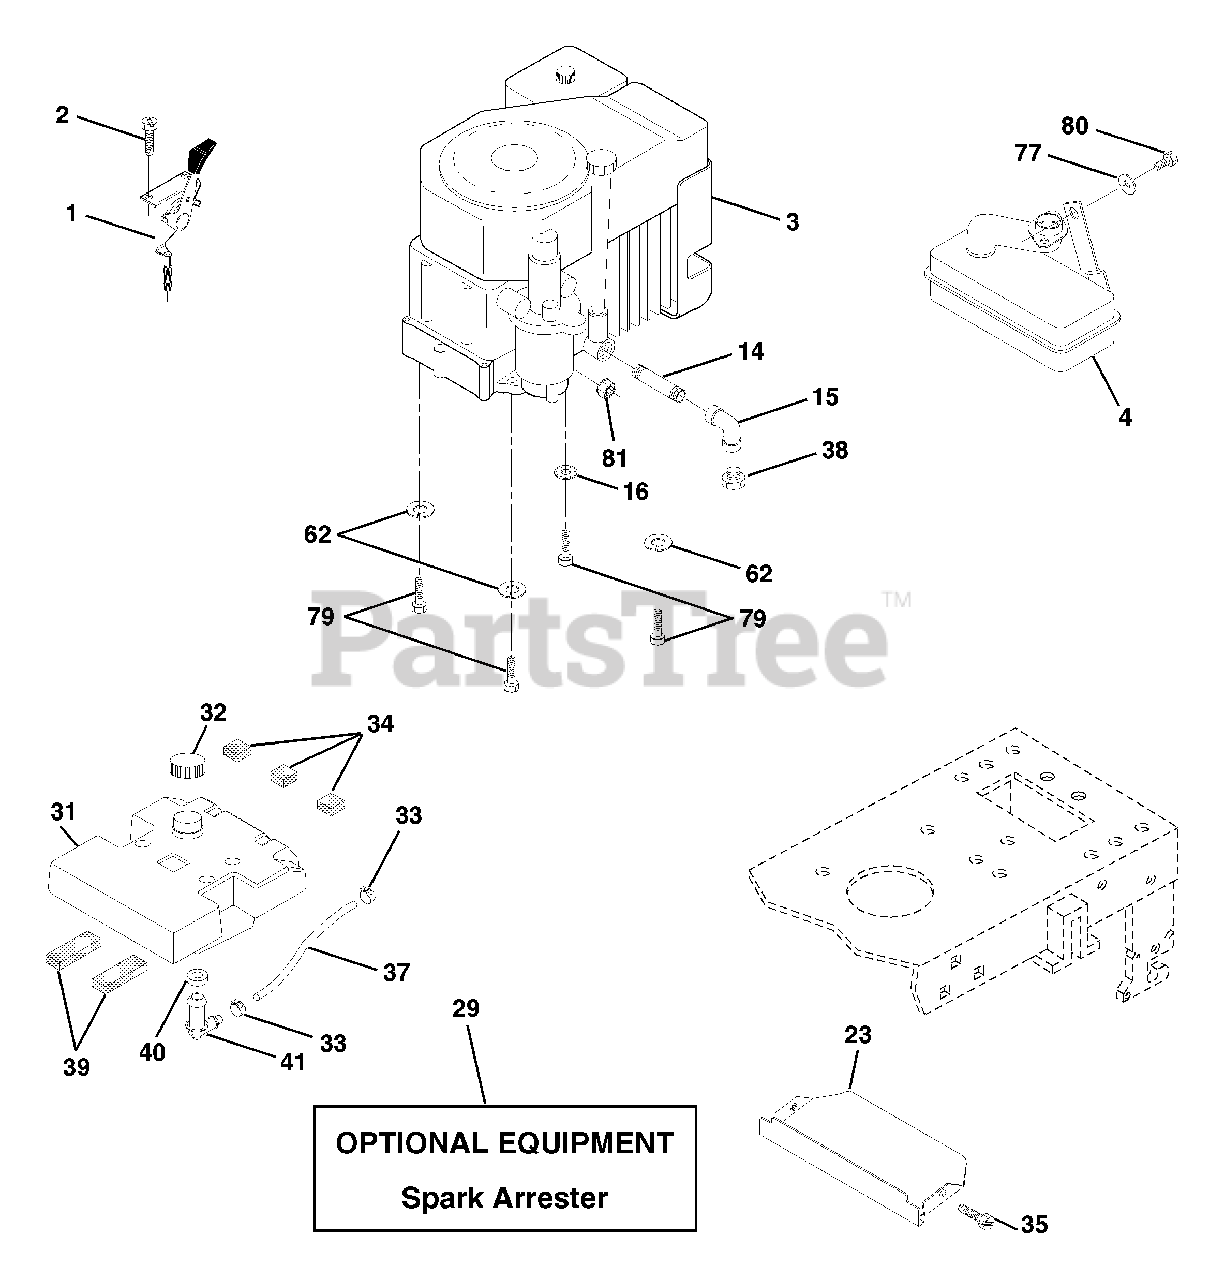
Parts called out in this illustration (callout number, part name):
1	Control Th/ch 27. LH. Flag Dom.
2	Screw Hex Thd Cut 1/4-20 x 5/8 T
4	Muffler LT Kohler 12.5/15HP
14	Nipple Pipe 3/8 Npt X 3-1/2
15	Elbow Std 90 Degree 3/8-18 Npt
16	Washer Lock Ext Tooth 5/16
23	Shield BRN/DBR Guard
29	Kit Spark Arrestor (Flat Scrn)
31	Tank Fuel 3.5 STLT W/O Sensor
32	Cap Asm Fuel W/sym Vented
33	Clamp Hose Black
34	Pad Spacer
35	Screw
37	Line Fuel 7.5"
38	Plug Oil Drain
39	Pad Idler 1.75 x .75 x .06
40	Bushing
41	Stem Tank Fuel
62	Washer Lock Hvy Hlcl Spr 5/16
77	Washer 5/16 x 3/4 x 16 Ga.
79	Bolt Hex
80	Bolt Hex Hd. 5/16-18 unc x 1/2
81	Nut Flange 1/4-20 Starter Nut
